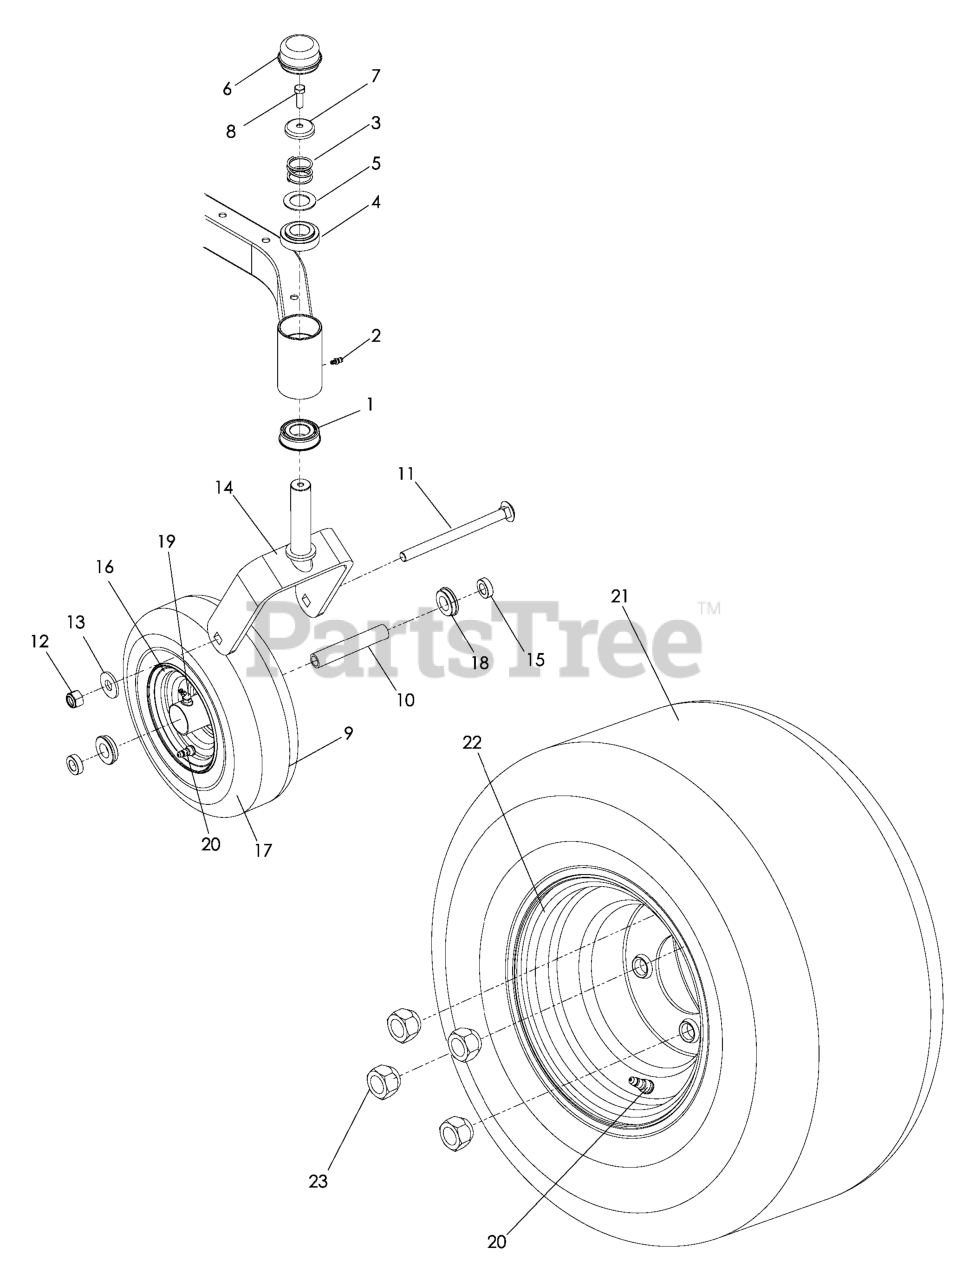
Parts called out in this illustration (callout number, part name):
1	BEARING FLANGED
2	ZERK, 3/16, DRIVE IN
3	SPRING, CASTER
4	BUSHING, CASTER
5	WASHER, 1.025 ID X 1.64
6	GREASE CAP
7	CASTER.PLUG
8	HCS 5/16C X 1
9	TIRE COMPLETE
11	RHSNB 1/2-13 X 6.50 GR2 ZD
12	NUT 1/2-13 HEX NYLOC ZD
13	WASH USS FLAT 1/2
14	YOKE.CASTER.ORANGE
15	SPACER, 5/16"
17	TIRE - CASTER
18	BEARING RETAINER
19	ZERK
20	VALVE STEM TR-412
21	TIRE ASM, 20 X 8-8
22	RIM.8X7.W/8".OFFSET.SILVER.ZTR
23	LUG NUT 1/2F
